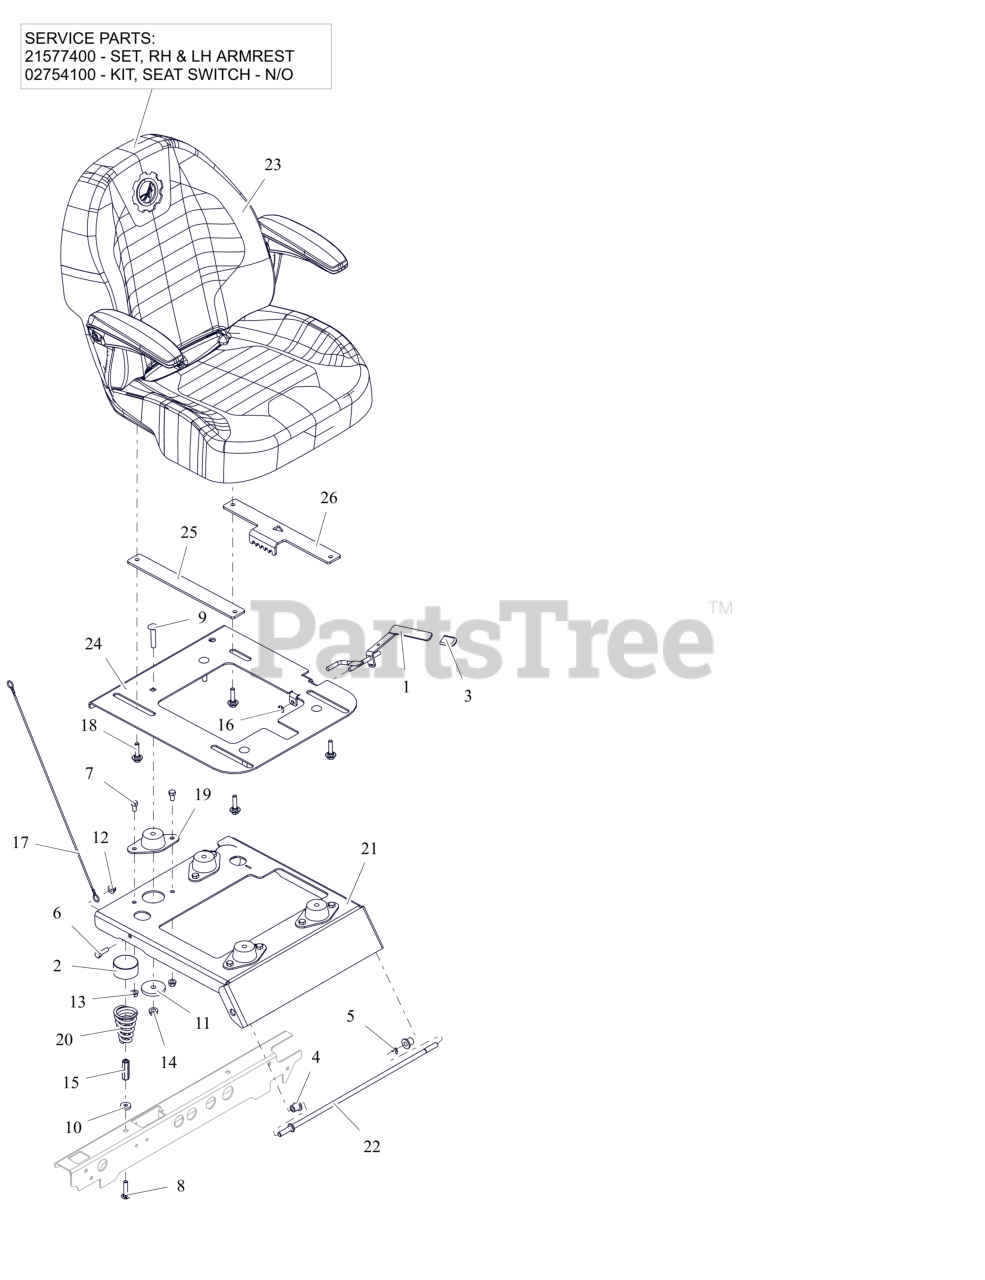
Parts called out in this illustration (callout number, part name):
1	WLDMT, SEAT SLIDE LEVER
2	HUB CAP
3	GRIP, SEAT LEVER, GREY
4	BSHG-FLG .38X.580X.667X.750
5	RG-RTNG-EXT .375X.035 TYP E
6	BLT,HEX .31-18X1.00 G5 ZCC
7	BLT, HEX .31-18X.625 G5 ZCC
8	BLT,RHSN .31-18X1.50 G5 ZCC
9	BLT,RHSSN.375-16X2.00 G5 ZCC
10	WSHR, FLT .328X.870X.179 ZCC
11	WSHR-FL-STL 0.406X2X0.25 ZCC
12	NUT,LK-NYL-FLG .31-18 G5ZC120
13	NUT,LK-CTR-FLG .31-18 GF ZCC
14	NUT-LK-CTR-FLG .375-16 GF ZCC
15	NUT, COUPLING .31-18X1.75 ZCC
16	NUT-PUSH .312
17	LANYARD, SEAT CABLE .093X19.5
18	BOLT SHLDR .31-18 X .175
19	MOUNT, FAIL-SAFE COMPRESSION
20	SPRING, SEAT
21	PLATE- SEAT (ISO MOUNT)
22	ROD- SEAT PIVOT
23	SEAT- IKON SPECIAL EDITION
23	SET, RH & LH ARMREST
23	SWITCH- SNAP MTG N.O.
24	PLATE- SEAT ISO - LIMITED
25	PLATE- SEAT SLIDE - LIMITED
26	PLATE- SEAT SLIDE ADJUST-LTD
